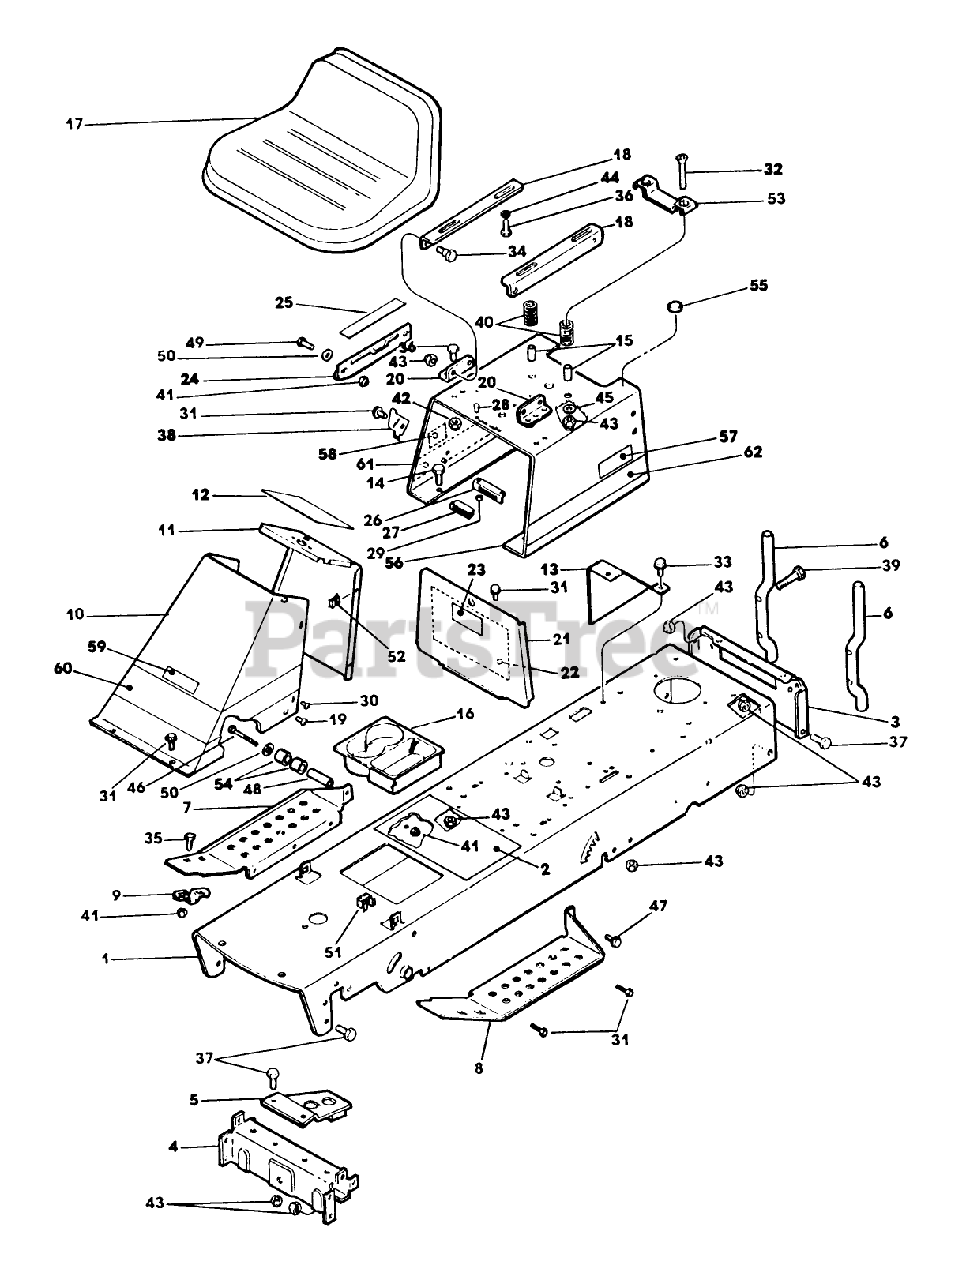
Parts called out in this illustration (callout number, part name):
3	HITCH PLATE* G
5	STEERING BRKT WA*G
11	STEERING TOWER W/D(12)
31	SCREW-THREAD FRMG
33	SCREW-HWH
35	SCREW-HH
36	SCREW - HEX
40	SPRING
41	NUT-LOCK, CONE
42	NUT
43	NUT-LOCKING
45	WASHER
49	SCREW
54	SPACER - RUBBER
